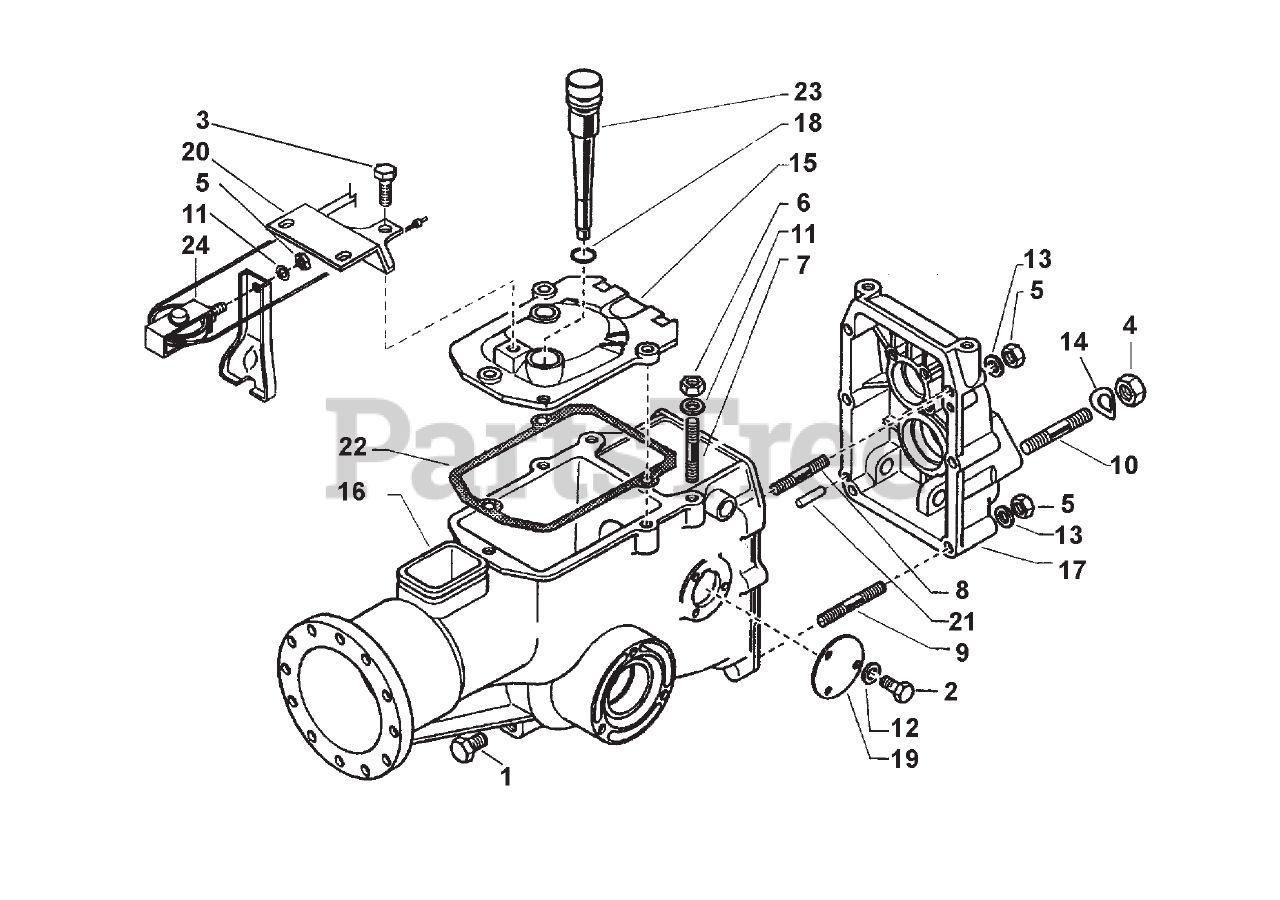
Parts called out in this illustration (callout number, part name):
2	SCREW, COUNTER SUNK, M6X16
3	CAP SCREW
4	NUT, M12X1.25
5	NUT, SELF LOCKING, M8
7	STUD, M8X38X14X20
8	STUD, M8X56X20X12
9	STUD, M8X68
10	STUD, M12X1.25X12X64
11	SUPER WASHER, M8
12	WASHER, LOCK, M6.4
13	WASHER, LOCK, M8.4
14	WASHER, DOME, M13
15	GEARBOX COVER
16	GEAR BOX CASE
17	REAR COVER
18	O RING
19	SIDE COVER
20	PLATE
21	PARALLEL PIN
22	GASKET, COVER
23	CAP WITH DIP STICK
24	PULLEY ASSEMBLY
